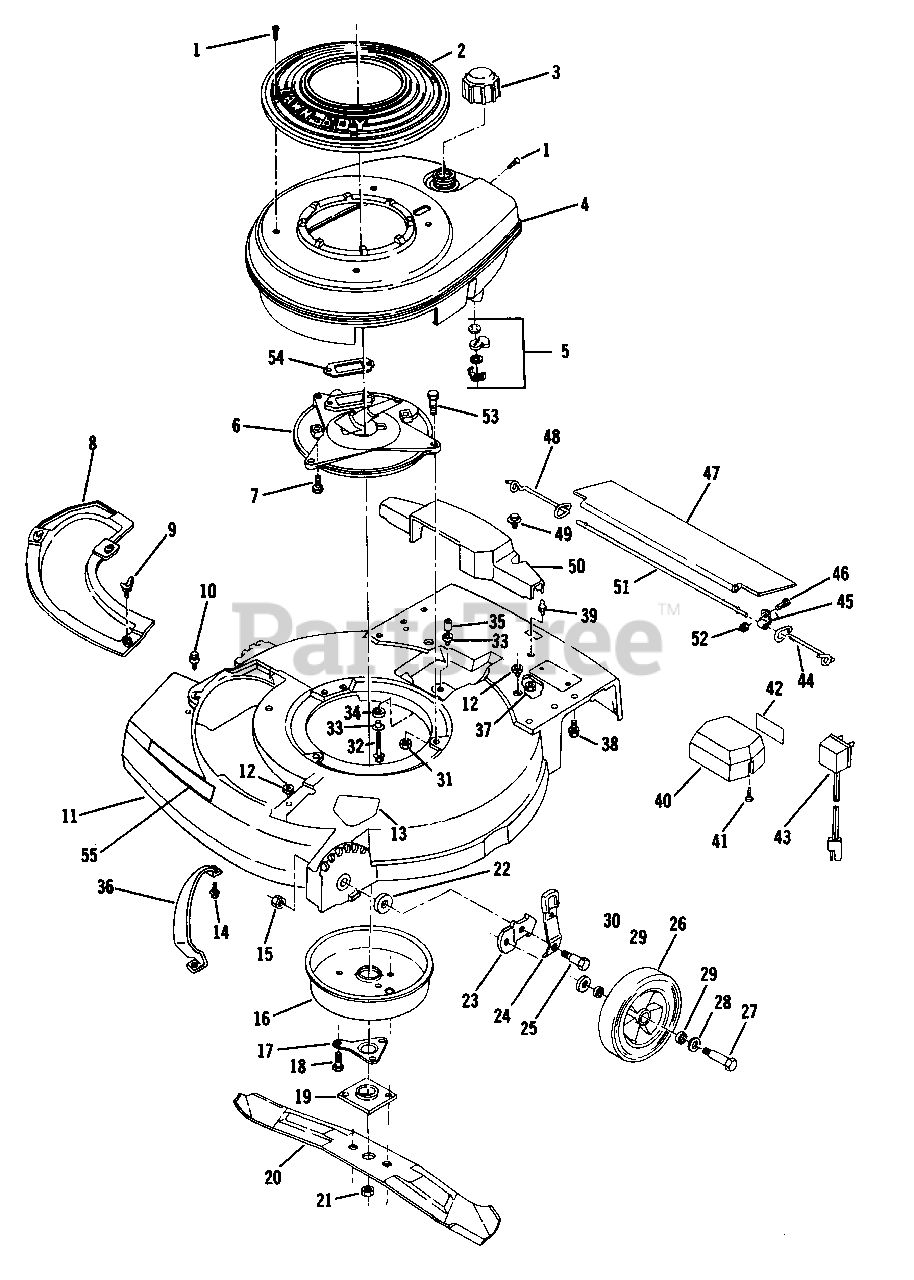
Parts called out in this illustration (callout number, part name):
1	Screw
2	Cover-Shroud
3	Fuel Cap
4	Shroud-Engine
5	Fuel Shut-Off Assembly
6	Plate-Muffler
7	Screw-Muff. Plt. to Blk.
8	Cover Plate
9	Wing Screw
10	Screw Plt. and Chute Mtg.
11	Housing
12	Grommet
13	Decal-Blade Contact Warning
14	Screw
15	Nut
16	Muffler Cover Assembly
17	Support-Crankshaft
18	Screw-Muff. to Muff. Plt.
19	Collar and Plate Assembly
20	Blade-21"
21	Nut-Blade
22	Washer
23	Bracket-Whl. Hgt. Adj.
24	Knob and Spring Assembly
25	Bolt-Shoulder
26	Wheel-Front
27	Bolt-Wheel-Front
28	Washer
29	Washer-Felt
30	Washer
31	Nut-Muff. Plt. to Housing
32	Screw
33	Spacer
34	Grommet
35	Spacer
36	Toe Bar
37	Nut-Ball Stud
38	Screw-Handle Bracket
39	Ball Stud-Batt. Mounting
40	Batt. Box and Batt. Pack Ass'y.
41	Screw
42	Decal
43	Battery Charger Assembly
44	Spring-L.H.
45	Clamp
46	Screw
47	Shield-Trailing
48	Spring-R.H.
49	Screw-Axle Cover Mounting
50	Cover-Drive Axle
51	Rod-Trailing Shield
52	Nut
53	Screw-Muff. Plt. to Hsg.
54	Gasket-Exhaust
55	Decal-Electric Restart
